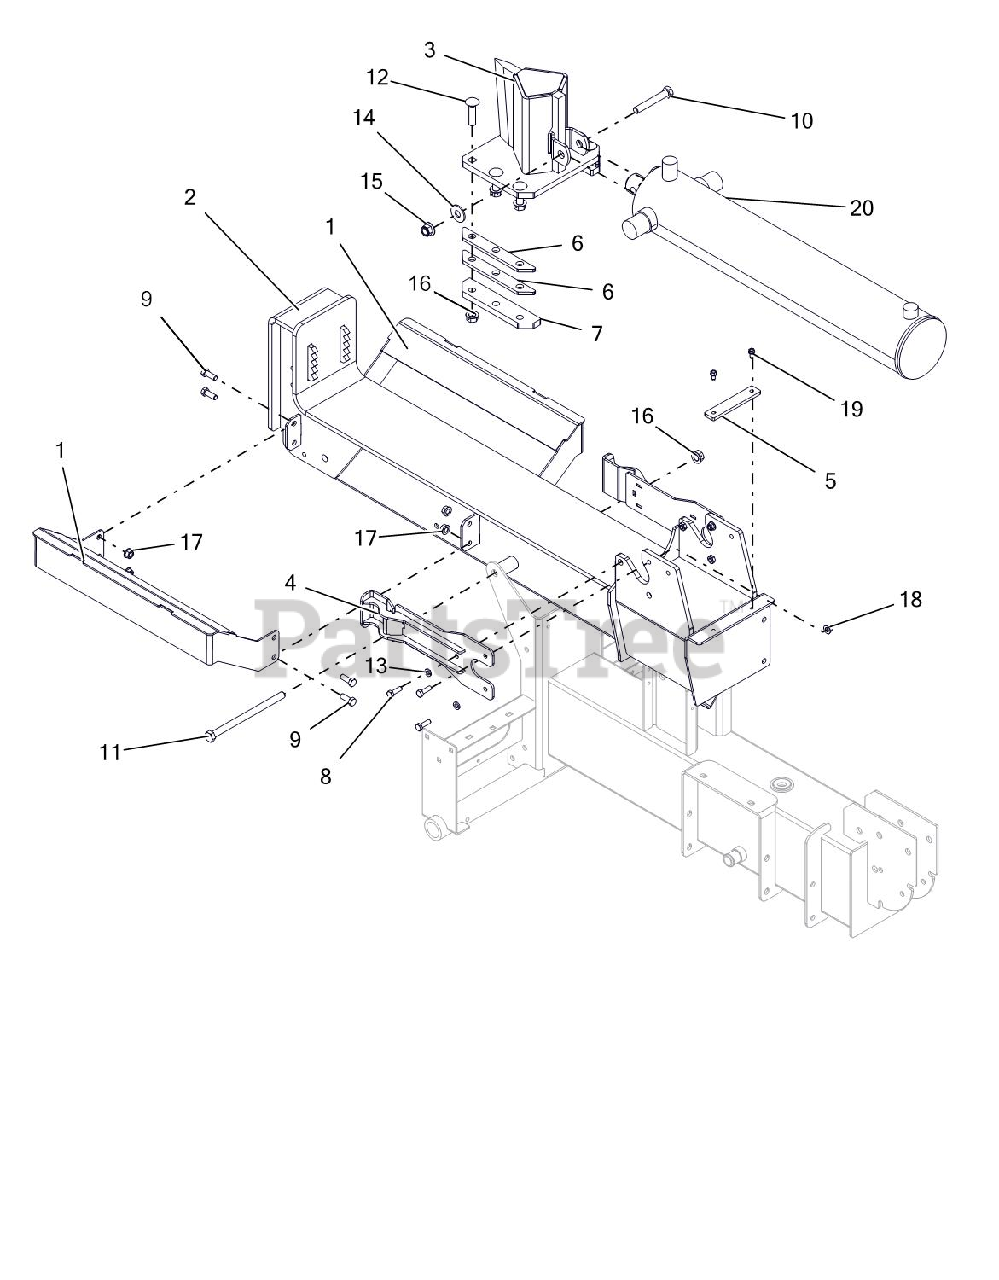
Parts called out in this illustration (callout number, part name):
1	WLDMT, CRADLE, LOG SPLITTER
2	WLDMT, BEAM - 27/34T SPLITTER
3	WMT, WEDGE - SPLITTER
4	WLDMT, PLATE - STRIPPER
5	SPACER, CYLINDER
6	SPACER, WEDGE
7	RETAINER,WEDGE
8	@BLT-HEX .31-18X1.00 GR5 YWZC
9	@BLT-HEX .38-16X1.00 GR5 YWZC
10	@BLT-HEX .50-13X3.25 GR5 YWZC
11	@BLT-HEX .50-13X7.50 GR5 YWZC
12	BLT-RDHDSQNKFTH.50-13X2 G8YWZC
13	WSHR-LK .312X.097 HVY YWZC
14	@WSHR-FL-STL.563X1.38X.109YWZC
15	@NUT-LK-NYL-FLG .50-13 YWZC
16	NUT-LK-CTR-FLG .50-13 YWZC
17	@NUT-LK-TOP-FLG .38-16 YWZC
18	@NUT-LK-TOP-FLG .31-18 YWZC
19	SCR-TAP .25-20X.50 HWH TR YWZ
20	CYLINDER,4.5 W/DECALS
